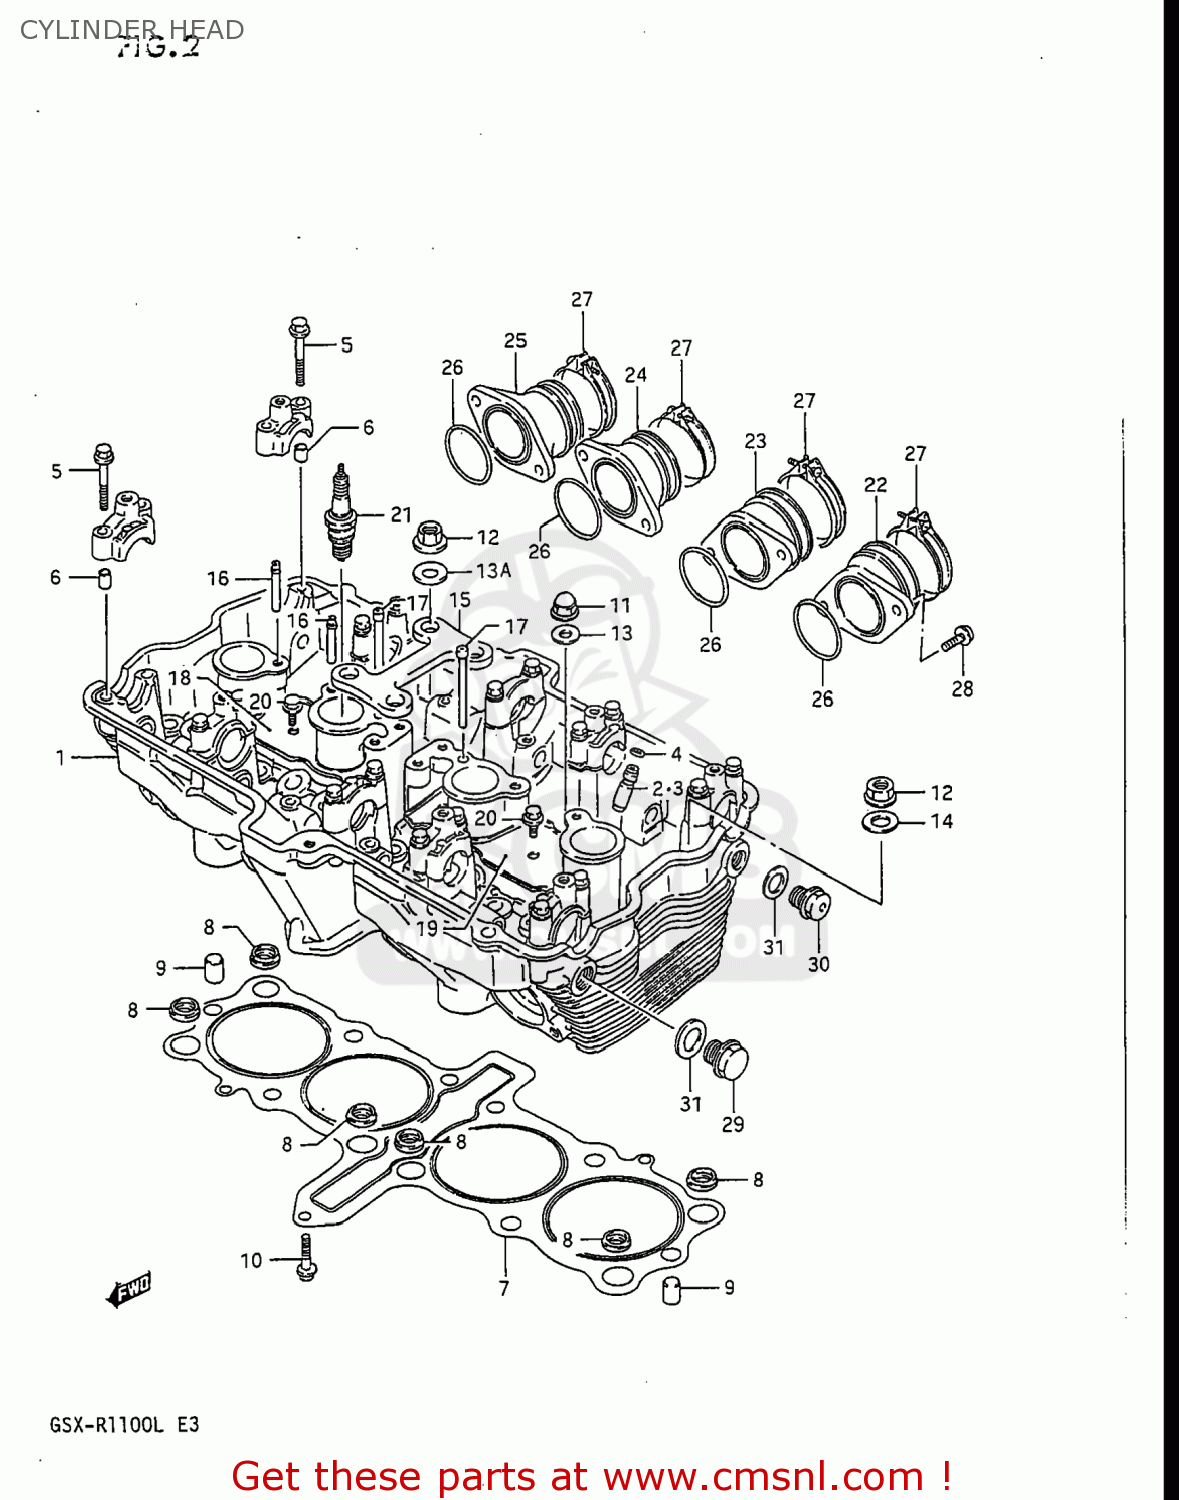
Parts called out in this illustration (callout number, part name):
1	HEAD ASSEMBLY,CYLINDER
2	GUIDE,VALVE
3	GUIDE,VALVE
4	RING,SNAP
5	BOLT(6X39)
6	PIN(6.2X8X11)
7	GASKET,CYLINDER HEAD (NAS)
8	O-RING,HEAD GASKET
9	PIN
10	BOLT
11	NUT
12	NUT
13	GASKET(10.2X20X2).3 (NAS)
13A	GASKET(10.2X20X2).3 (NAS)
14	WASHER (10.5X22X2.3)
15	PLATE,HEAD REINF
16	PIPE,OIL NO.1
17	PIPE,OIL NO.3
18	PLATE,OIL PIPE,R
19	PLATE,OIL PIPE,L
20	BOLT
21	PLUG,SPARK(JR9B)
22	PIPE,INTAKE
23	PIPE,INTAKE
24	NET,INTAKE
25	PIPE,INTAKE
26	O RING(D:2.4,ID:39.7)
27	CLAMP
28	SCREW
29	PLUG
30	PLUG
31	GASKET(14X19.2X2) (NAS)
